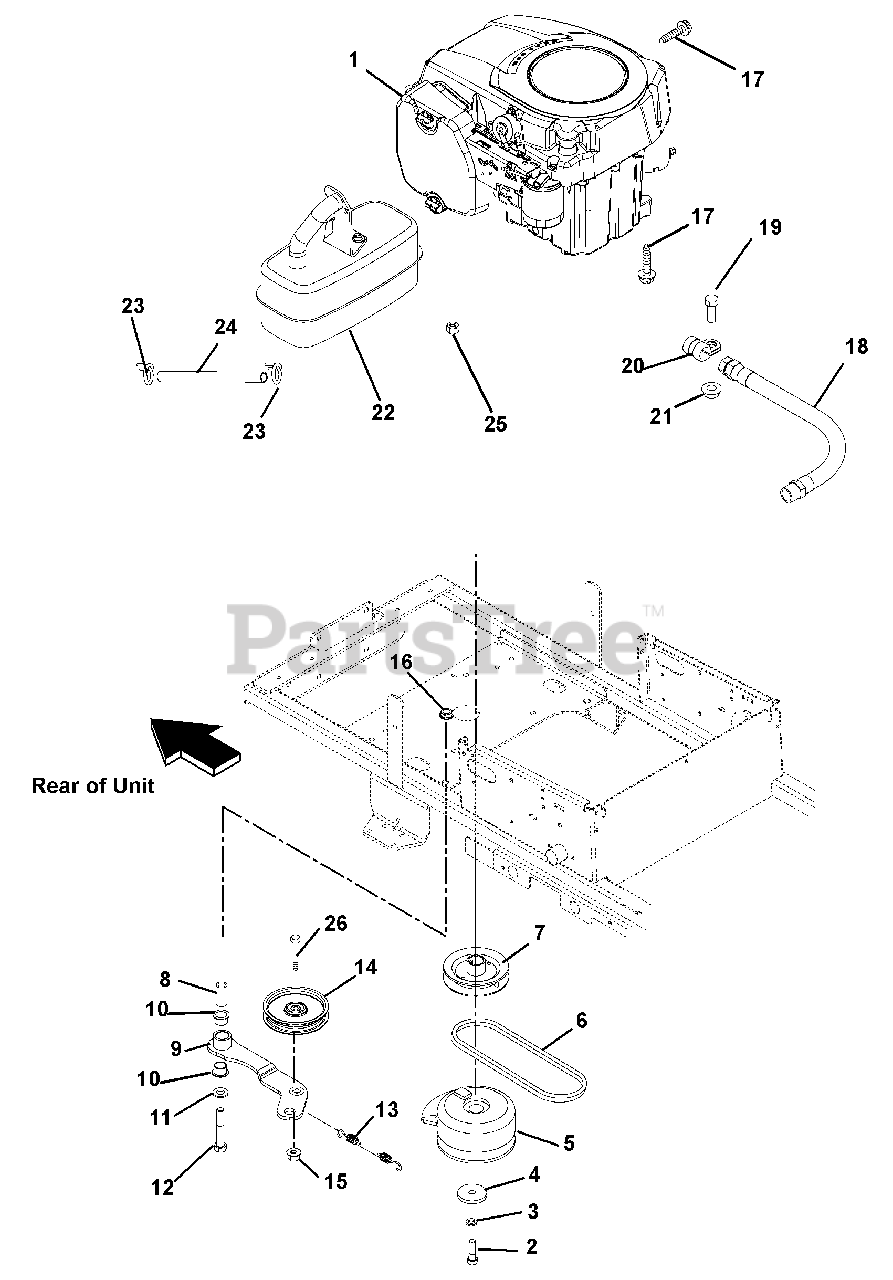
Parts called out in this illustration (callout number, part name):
1	Engine, 16 HP Kohler Single
2	7/16 - 20 x 3-1/4 HHCS Grade 8
3	Washer, Locking .44 x .109 Regular
4	Washer, Flat Steel .469 x 2.00 x .25
5	RMS Clutch, Electric
6	Belt, HA 61.24 Wrapped
7	Sheave, Ground Drive
8	Bushing, Sleave .500 x .750 x .1.560
9	Weldment, Idler
10	Bushing, Flange .75 x .875 x .625 x 1.125
11	Washer, Flat Steel .531 x 1.06 x .095
12	Bolt, Hex .50-13 x 3.25
13	Spring, Extension
14	Idler, Flanged 4.00
15	Nut, .38-16 Flange Nyloc
16	Nut, Locking Top Flange .50-13
17	Screw, Tapping .38-16 x 1.00 Hex Washer Head
18	Hose, Hydraulic, .38-11-0K M6N0-F6J0
19	Bolt, Hex .31-18 x .75 Grade 5
20	Clamp, Cushioned Steel .75
21	Nut, .31-18 Nyloc Flange
22	Muffler, Weldment
23	Clamp, Hose Wire .490/.510 x .116
24	Gas Line, Bulk 1/4" I.D.x 28"
25	Nut, Top Lock Flange 8 x 1.25
26	Bolt, Hex .38-16 x 2.00 Grade 5
